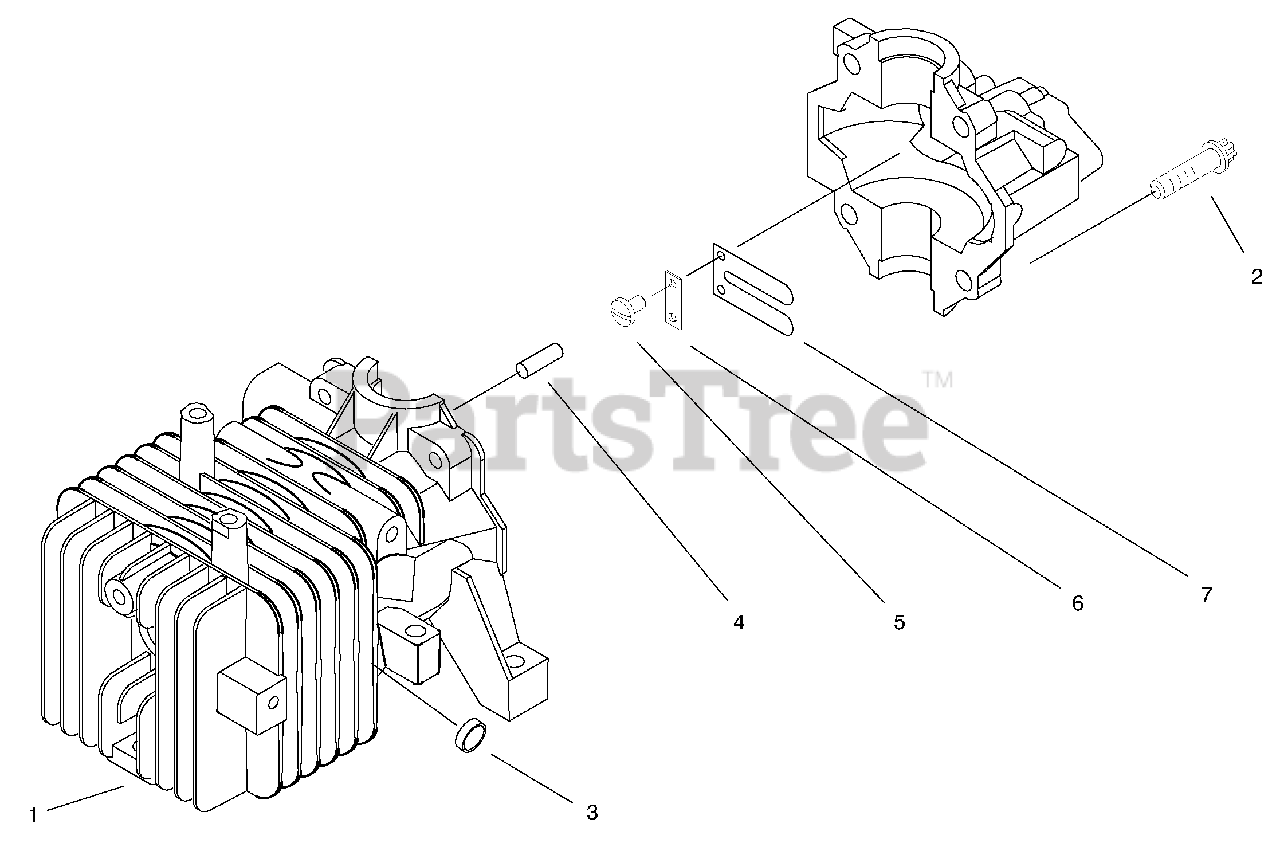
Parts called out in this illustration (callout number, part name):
1	Cyl & Crankcase ASM
2	Screw-HWH
3	Plug-Core
5	Screw-Slotted Head
6	Reed-Backup Plate
7	Reed-Carburetor
